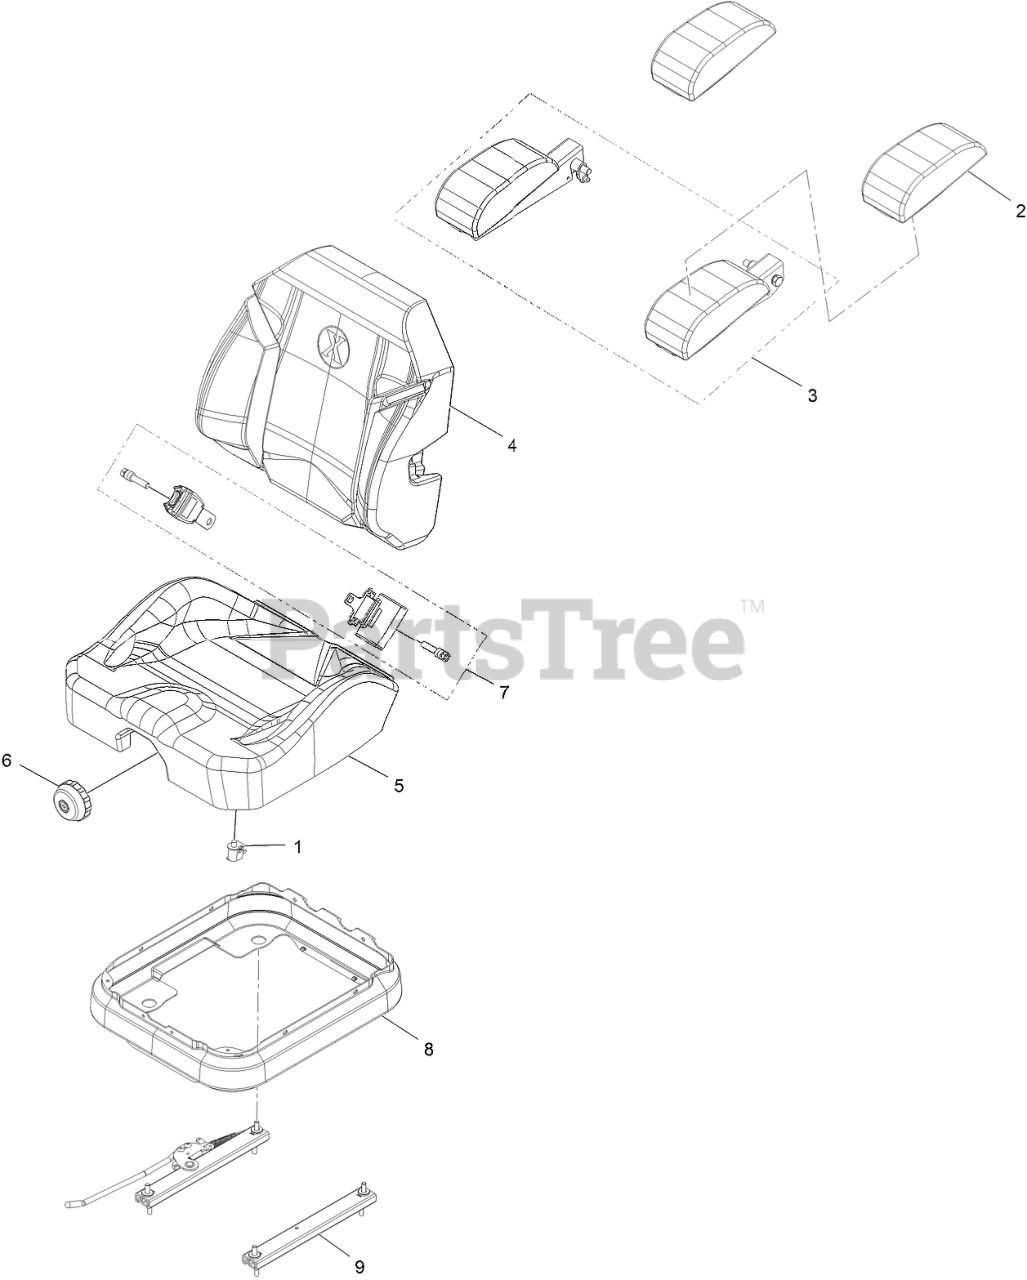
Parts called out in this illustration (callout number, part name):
1	SWITCH-BAIL
2	KIT-ARM REST PADS
3	KIT-ARM REST SET
4	COVER-BACK 311463VN500
5	COVER-CUSHION 311464VN500
6	KNOB-ADJUSTER
7	SEAT BELT SERVICE KIT
8	COVER-SUSPENSION BELLOWS
9	SET-SEAT TRACK
